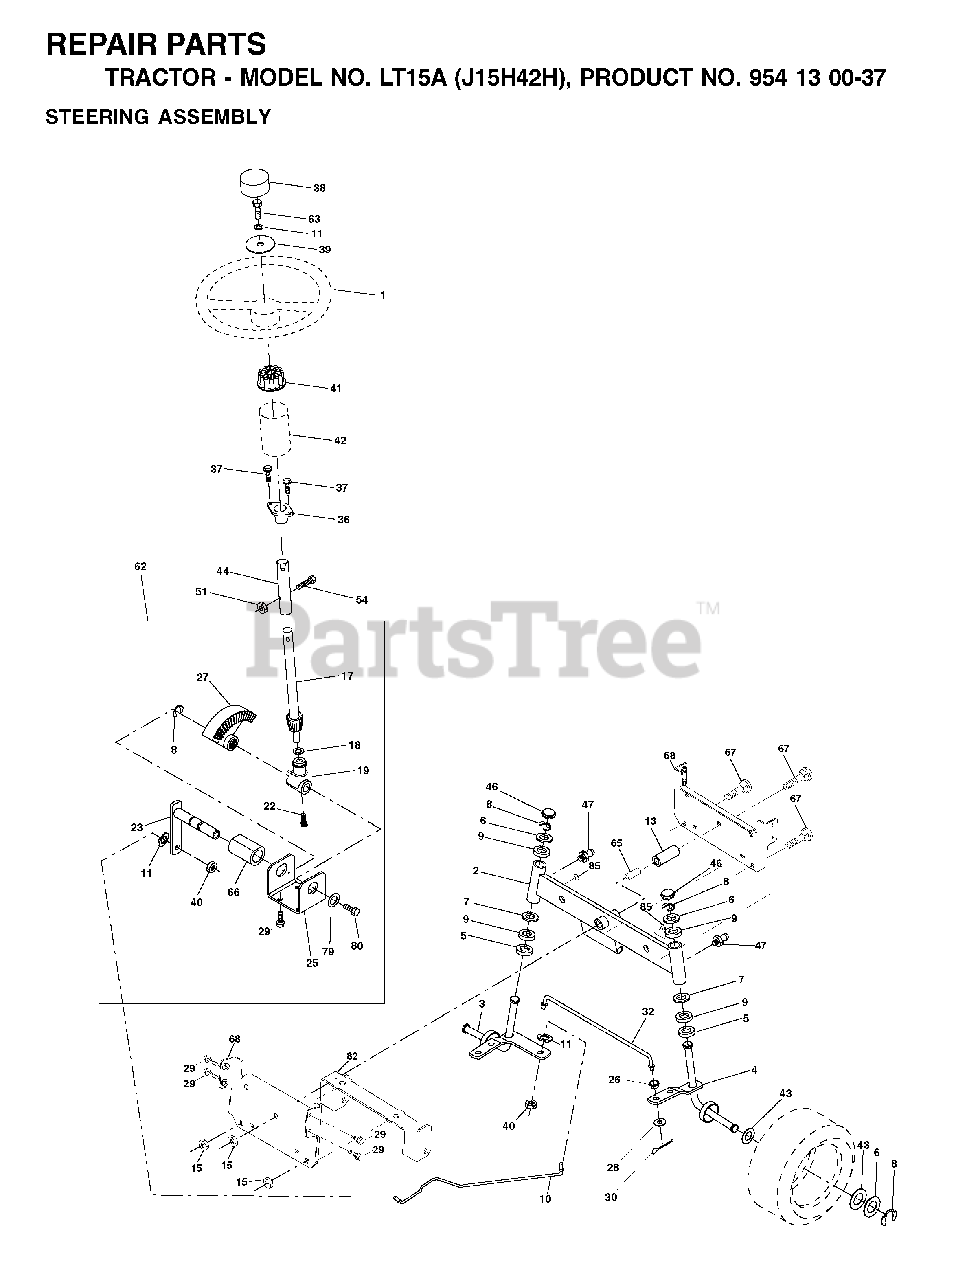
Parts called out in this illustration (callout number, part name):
2	AXLE ASSY
3	SPINDLE.ASM.LH.15"TIRES
4	SPINDLE.ASM.RH.15"TIRES
8	RING CLIP
9	BRNG T
10	DRAGLINK.15".TIRES
11	WASHER, LOCK 3/8
13	TUBE, PIVOT AXLE
15	NUT
17	SHAFT ASM STEERING
18	THRUST WASHER
19	STEERING SHAFT SUPPORT
22	SCREW.HX.WSH.HD
23	SHAFT ASSY PITTMAN
25	BRACKET STEERING
26	BUSHING.DRAGLINK
27	GEAR.SECTOR
28	WASHER
29	SCREW 3/8-16X3/4
30	COTTER PIN
32	TIE ROD
36	BUSHING, STEERING
39	WASHER 13/32 X 2-3/8 X 12 GA
40	GRIPCO NUT
41	STEERING WHEEL ADAPTOR
42	BOOT.STEERING.SHAFT.BLACK
44	EXT SHAFT STEERING
46	CAP.SPINDLE
47	ZERK M
51	NUT.71038.31-18.HEX.NYLOCK
54	BOLT.5/16-18X1-1/4 FULL.THREAD
62	STEERING KIT
65	SPACER BRACE AXLE
66	BEARING ARM
67	BOLT
68	BRACE.AXLE.15"TIRES
80	BOLT.HX.NYLON3/8-16X
82	BRACKET
85	FASTENER.XMAS.TREE
